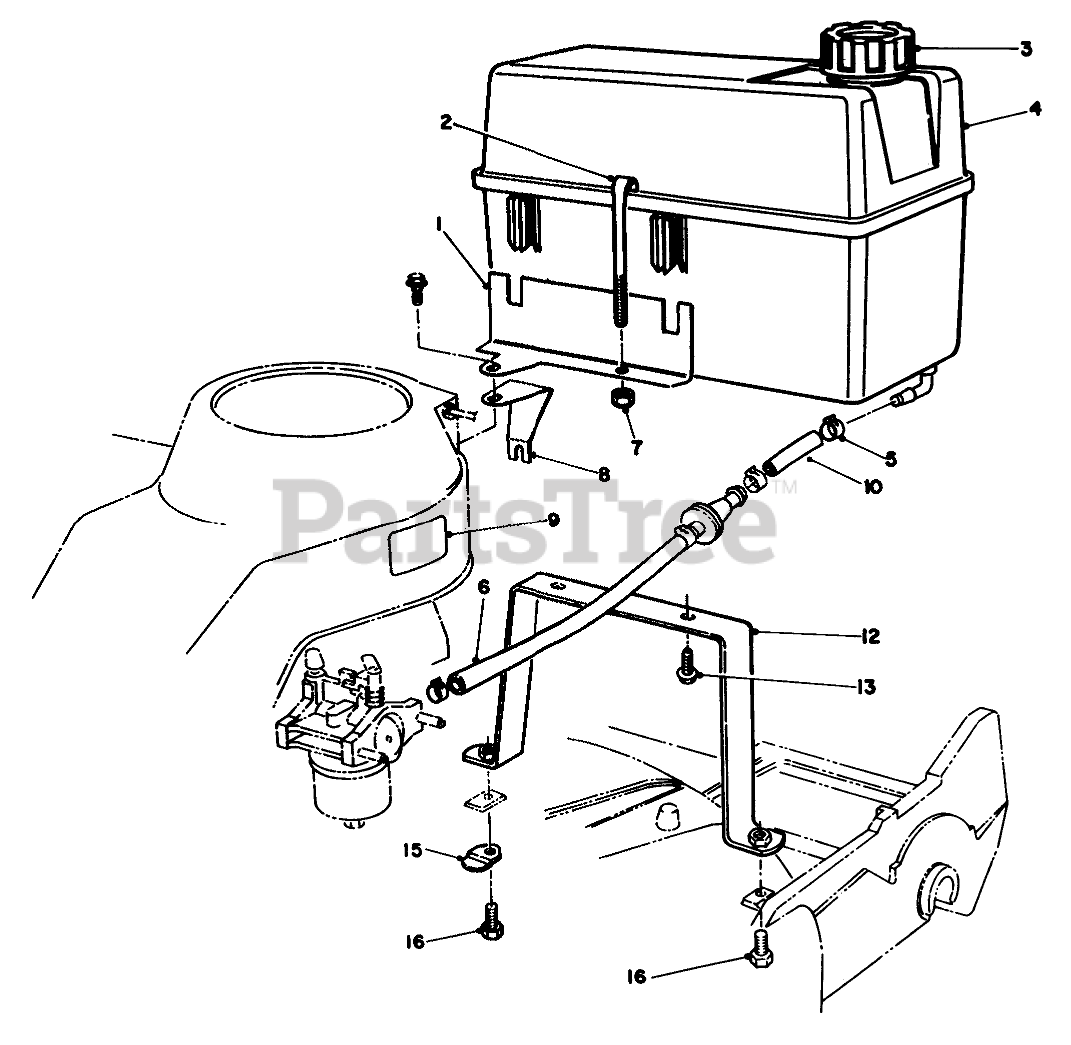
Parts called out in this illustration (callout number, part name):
1	Bracket Tank
2	RETAINER - FUEL TANK
3	GAS CAP ASM
4	Tank-Gas
5	CLAMP-FUEL LINE
6	HOSE-FUEL
7	NUT-LOCK, NI
8	Support-Bracket
9	DECAL - FUEL
10	LINE-GAS
11	FILTER-FUEL
12	Base-Tank
13	SCREW-HWH
15	SHIELD-RETAINER
16	SCREW-HH
